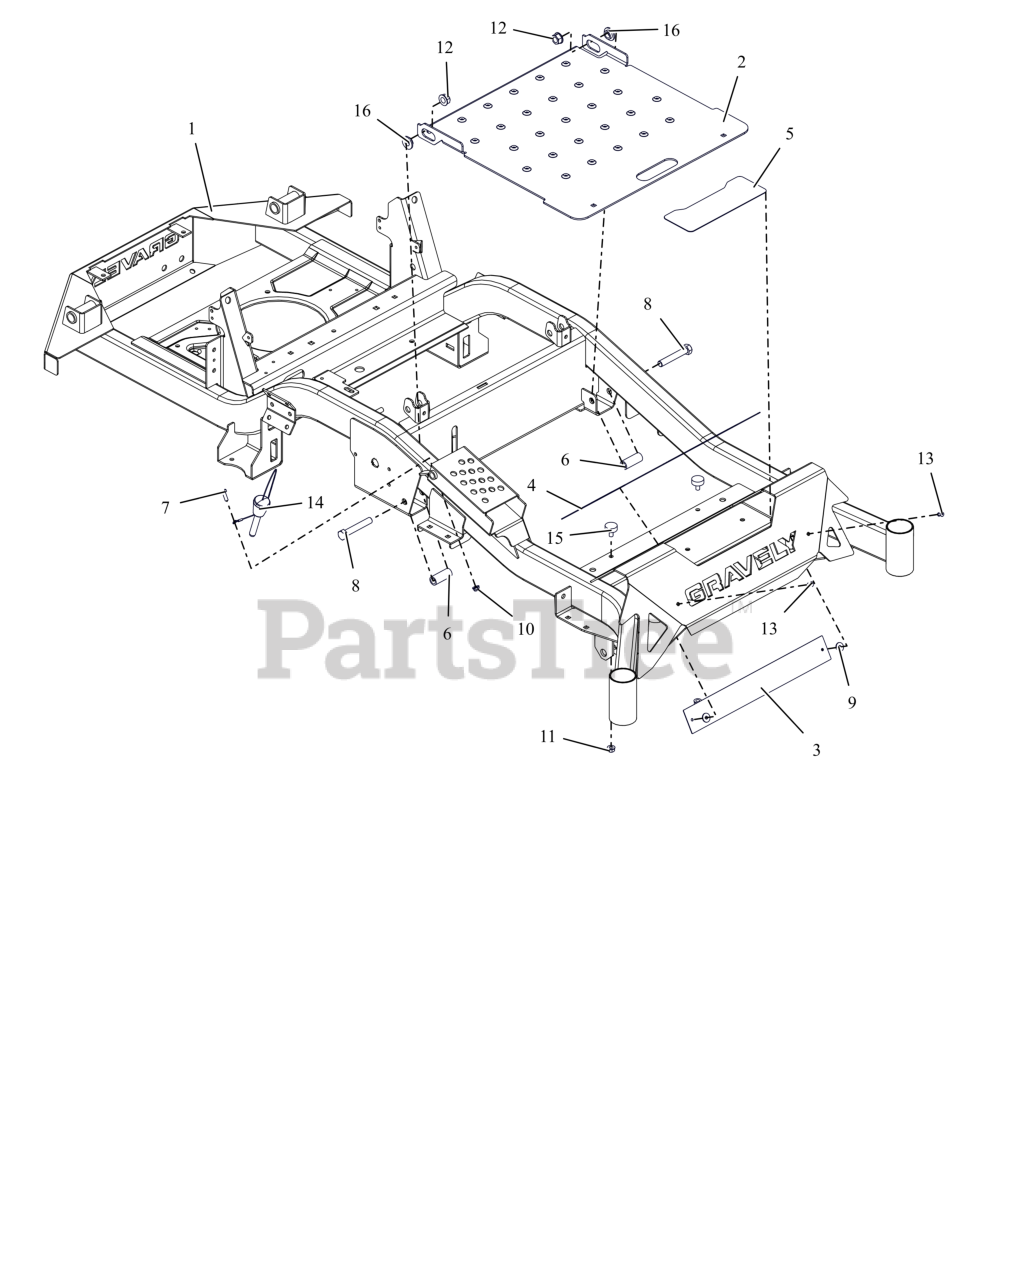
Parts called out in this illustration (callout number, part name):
1	WLDMT, MAIN FRAME -HD 44/52
2	KIT,ACCESS PANEL W/DECALS-RED
3	PLATE, BACK FOOT-REST XL
4	GRIP, FRONT
5	GRIP, STEP
6	SPACER, .515X.75X1.83
7	BLT, HEX .25-20X.75 G5 ZCC
8	BLT, HEX .50-13X3.00 G5 ZCC
9	WSHR, RBR W/ADHESIVE .25X.75X.06
10	NUT,NYL-FLG .25-20 GF ZCC
11	NUT,SPNLK-FLG .31-18 G5 ZCC
12	NUT-LK-TOP-FLG .500-13 GF ZCC
13	RIVET, #66 STEEL POP PD BLACK
14	PIN, MAGNETIC .50X2.50
15	BUMPER, RUBBER
16	BSHG-FLG .515X.750X.310X1.120
